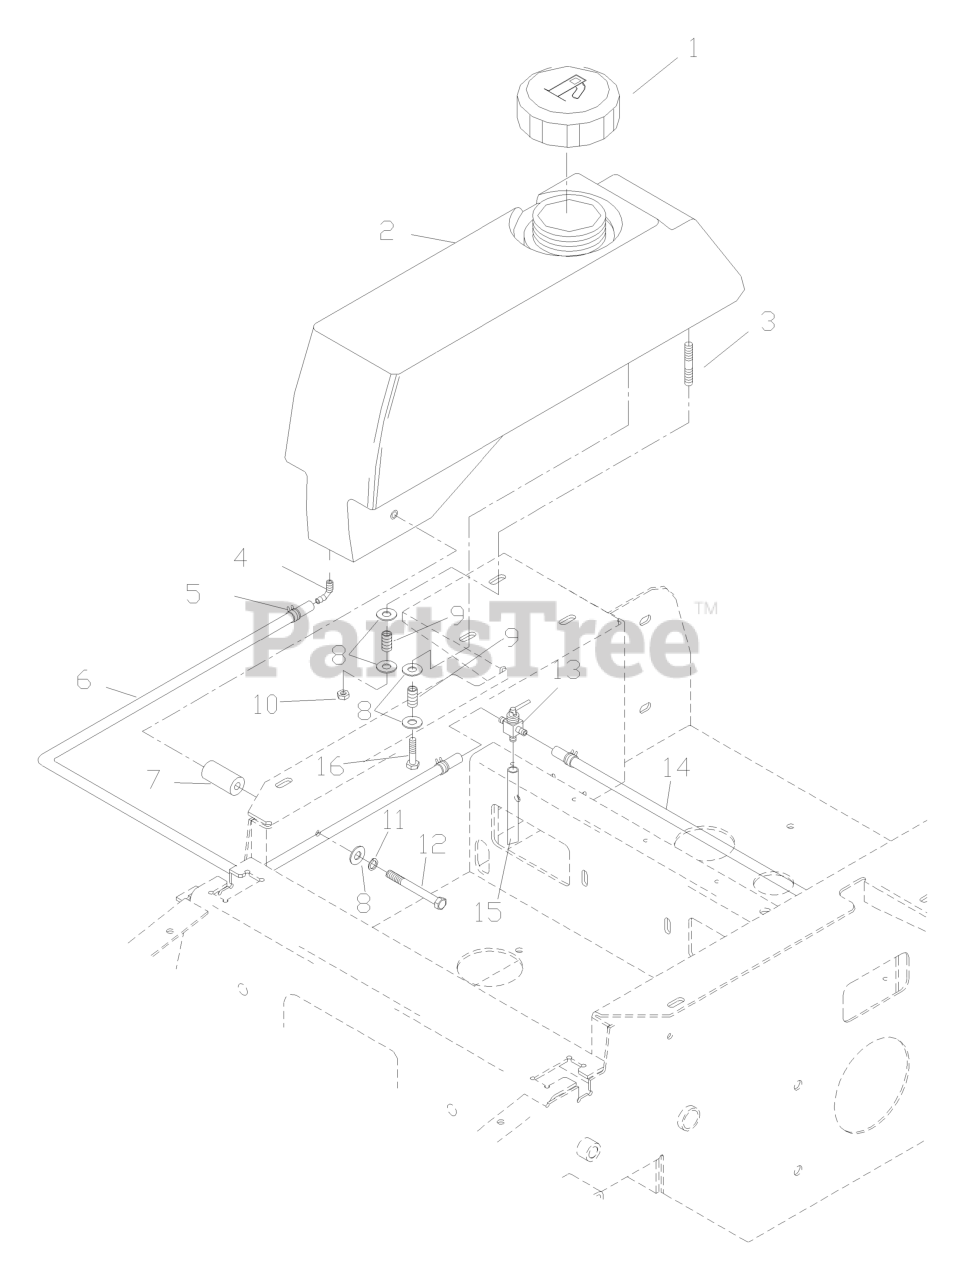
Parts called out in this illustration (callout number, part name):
1	FUEL CAP ANTI-SPLASH
2	FUEL TANK RT
2	LEFT TANK W/CUP HOLDER
3	STUD, 5/16C
4	HOSE BARB 90 DEGREE
5	HOSE CLAMP
7	TANK SPACER
8	WASHER 5/16 FLAT
10	NUT 5/16 NYLOC
11	WASHER.LOCK.HVY.HLCL.SPR.5/16
12	HCS 5/16C X 4
13	FUEL VALVE
15	FUEL LINE 29.5"
15	FUEL LINE 16"
16	HCS 5/16C X 1
